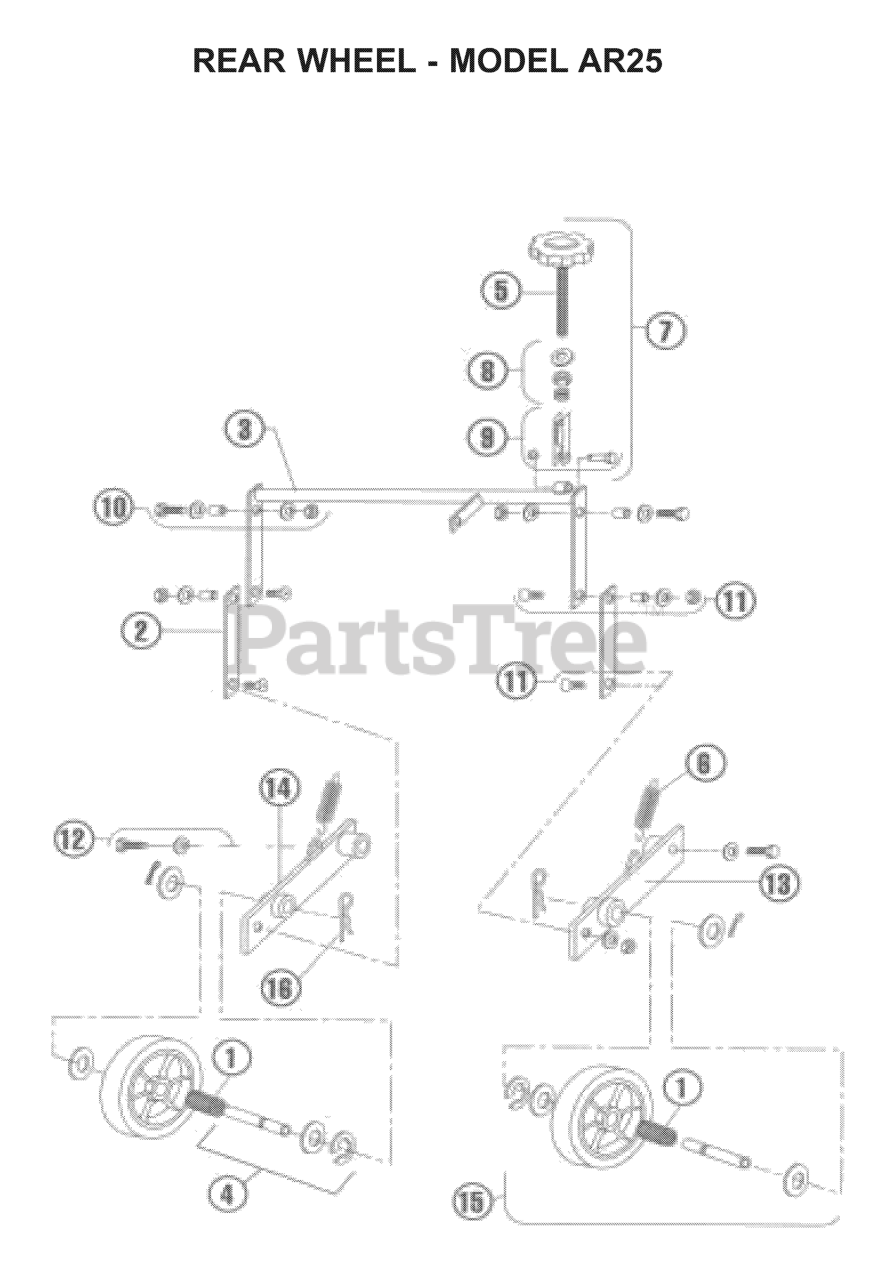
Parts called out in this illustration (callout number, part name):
1	BEARING, ROLLER
2	LIFT ARM LINK LWR ORN
3	KIT, TORQUE ARM
4	AXLE KIT
5	KNOB, DEPTH/STABILITY
6	SPRING, IDLER CAM, 3 3/4"
7	KIT DEPTH CONTROL STABILITY
8	KNOB SPRING KIT
9	BRACKET KIT
10	FASTENER KIT
11	FASTENER KIT, LINKAGE
12	FASTENER KIT
13	WHEEL ARM
14	WHEEL ARM
15	REAR WHEEL, COMPLETE
16	COTTER KEY
